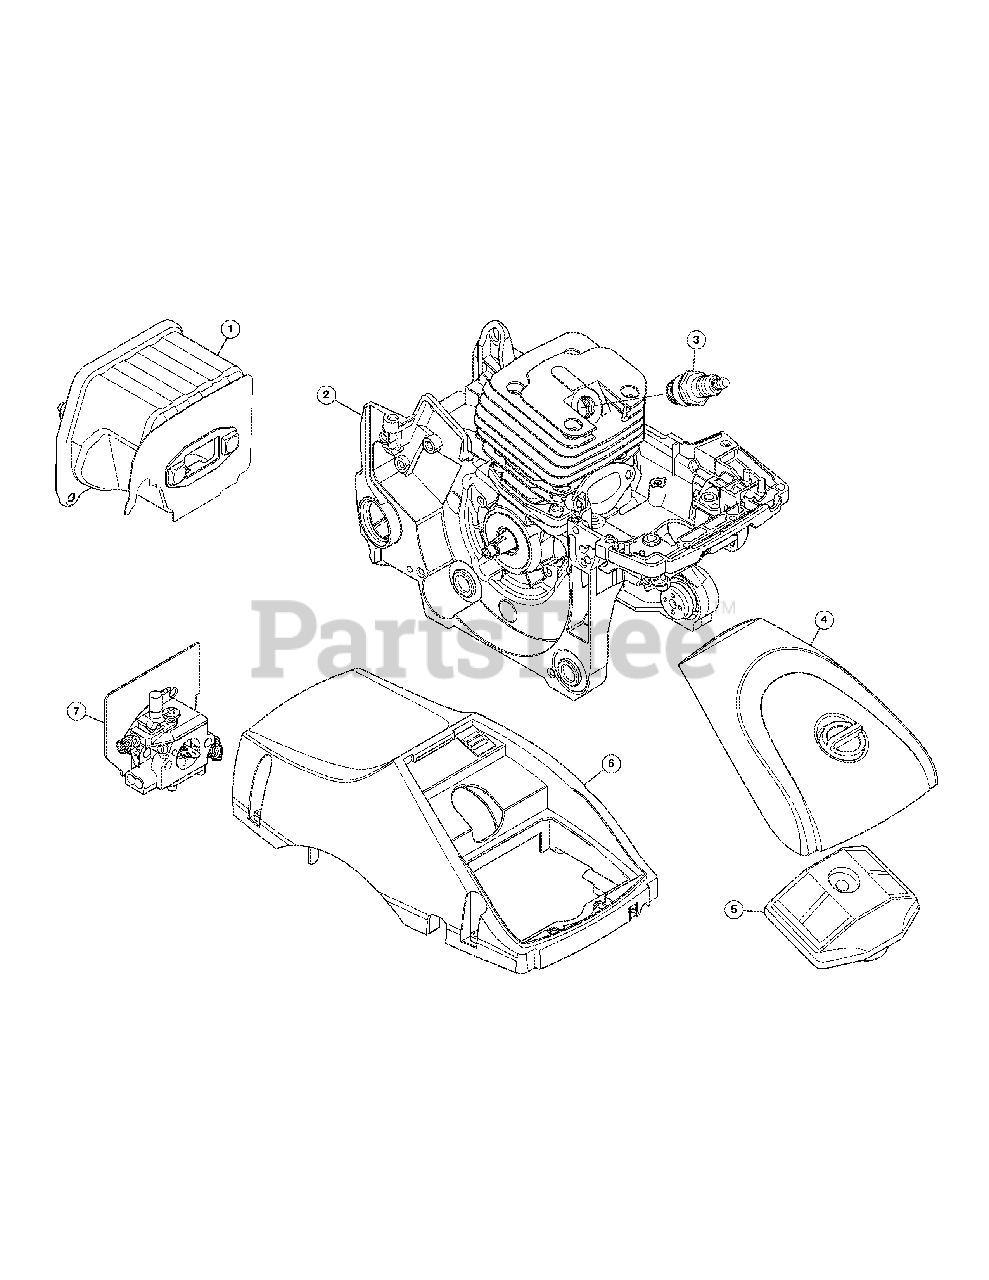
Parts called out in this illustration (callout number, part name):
1	Muffler Assembly
2	42cc Short Block Assembly
3	Spark Plug
4	Air Filter Cover Assembly
5	Air Filter
6	Cylinder Cover Assembly (with Plate and Screws (5))
7	Carburetor Assembly
